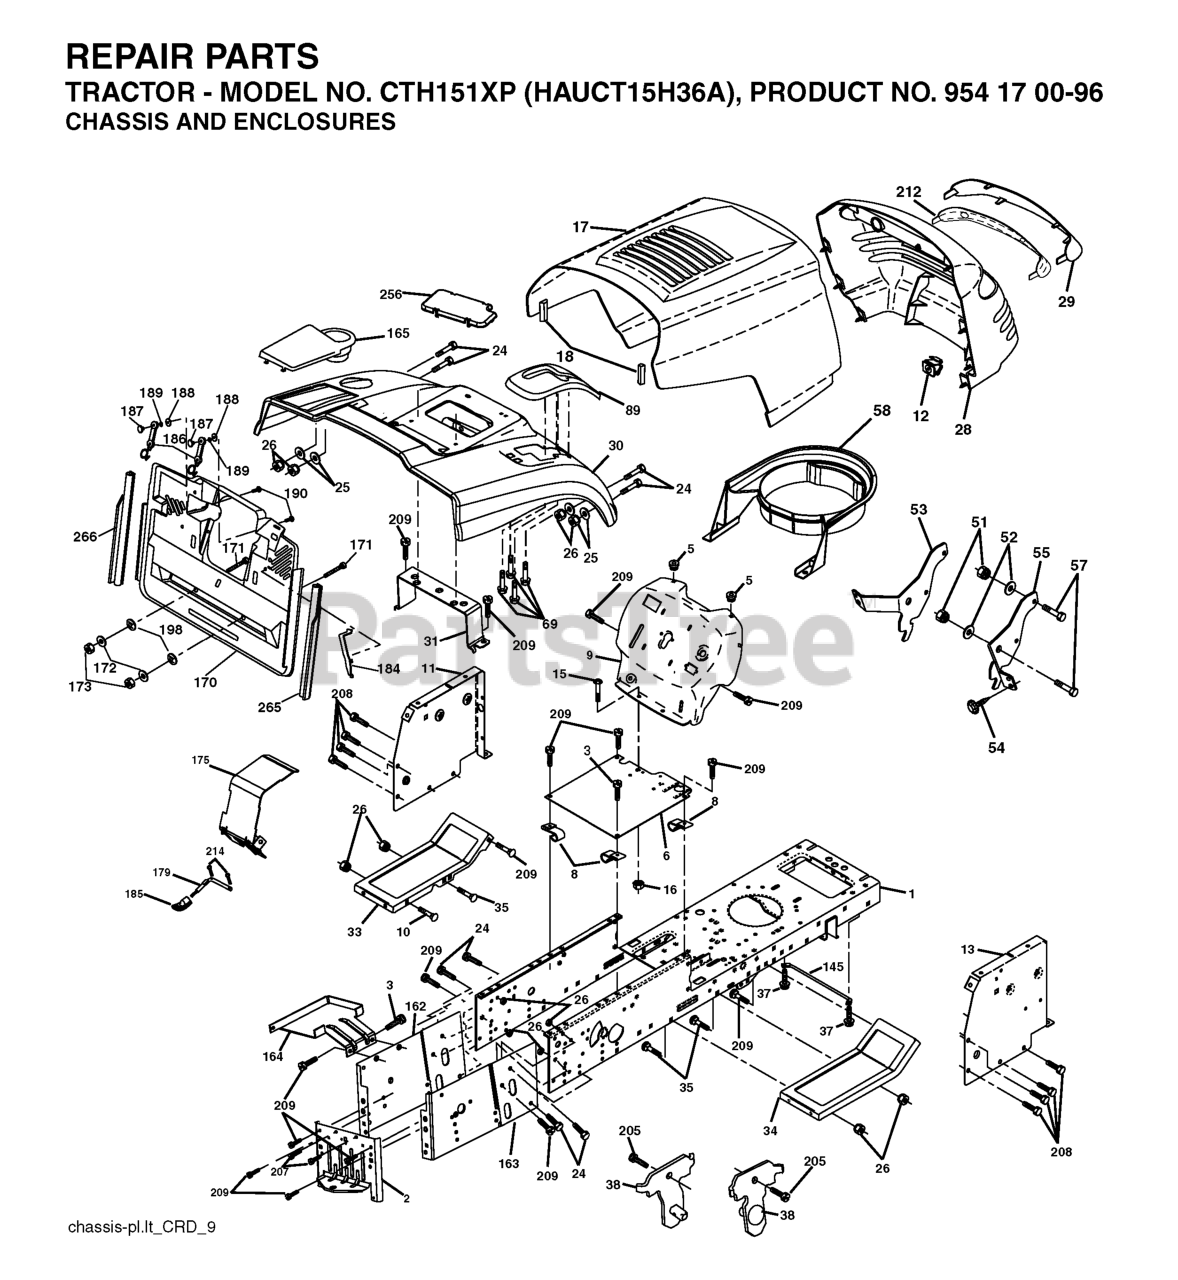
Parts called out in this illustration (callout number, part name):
2	DRAWBAR
3	SCREW 3/8-16X3/4
5	BUMPER.RUBBER.HOOD
6	PLATE
8	CLIP,INSULATOR
10	BOLT D
11	PANEL.DASH.LH.LTX
13	PANEL ASM, DASH RH
15	Screw, Machine, Truss Head 5/16-18 UNC x 3/4
16	NUT
17	HOOD ASM.
18	BUMPER.HOOD.LARGE.1.75"
24	BOLT
25	WASHER
26	NUT
28	GRILLE/LENS ASM
29	LENS
31	BRACKET SUPPORT FENDER
33	FOOTREST PNT LH
34	FOOTREST PNT RH
35	BOLT
37	Screw 5/16-18 x 1/2 Hex, Self Tapping 5/16-18 x 1/2
38	BRACKET ASM PIVOT MOWER REAR
51	LOCKNUT.NYLOC.1/4-20
52	WASHER
53	BRACKET.GRILLE.LH
54	SCREW.HEX.WS.HD.8-18 X 7/8
57	BOLT
69	SCREW.HI-LO.CONSOLE
89	COVER.BATTERY.CRD.GREY
145	ROD PIVOT CHASSIS/HOOD
162	BRACKET
163	BRACKET EXTEN CHASSIS RH CRD
165	RP.COVER.BATTERY.CRD.GREY
171	BOLT
172	WASHER
184	BRACKET.ACTUATOR.BAGGER.SRD
186	LATCH ASSY
187	WELDNUT
189	LOCKWASHER #10
190	SCREW
205	SCREW LT
207	SCREW, 5/16-18 X 1/2
208	SCREW 3/8-16X1/2
209	SCREW, 3/8-16X3/4
212	REPL BY 532 1745-03
214	RETAINER M
256	COVER FENDER CRD
265	SEALING
266	SEALING
